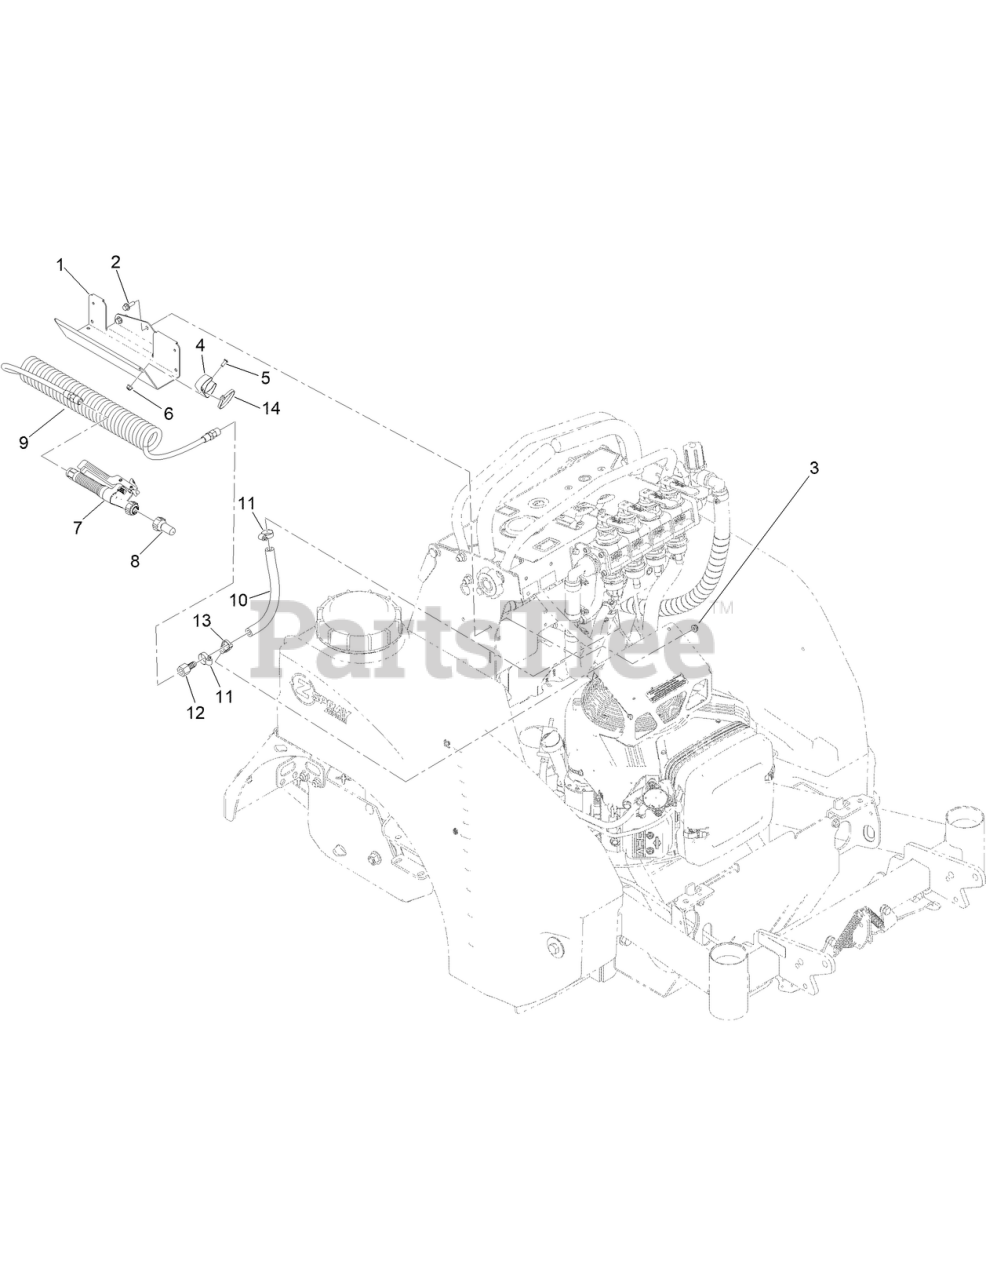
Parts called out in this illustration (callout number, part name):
1	TRAY-HOSE
2	Screw-HHF
3	Nut-Hex Flange
4	Holder-Tool, Clip
5	Screw-HSBH
6	Nut-Hex Flange
7	GUN-SPRAY, SPOT
8	TIP-SPRAY, #12 SPOT
9	HOSE-COILED, 15 FT
10	Hose-Spray
11	CLAMP-HOSE
12	Fitting-Female, Barbed
13	CLIP-TIE
14	TIE-CABLE
